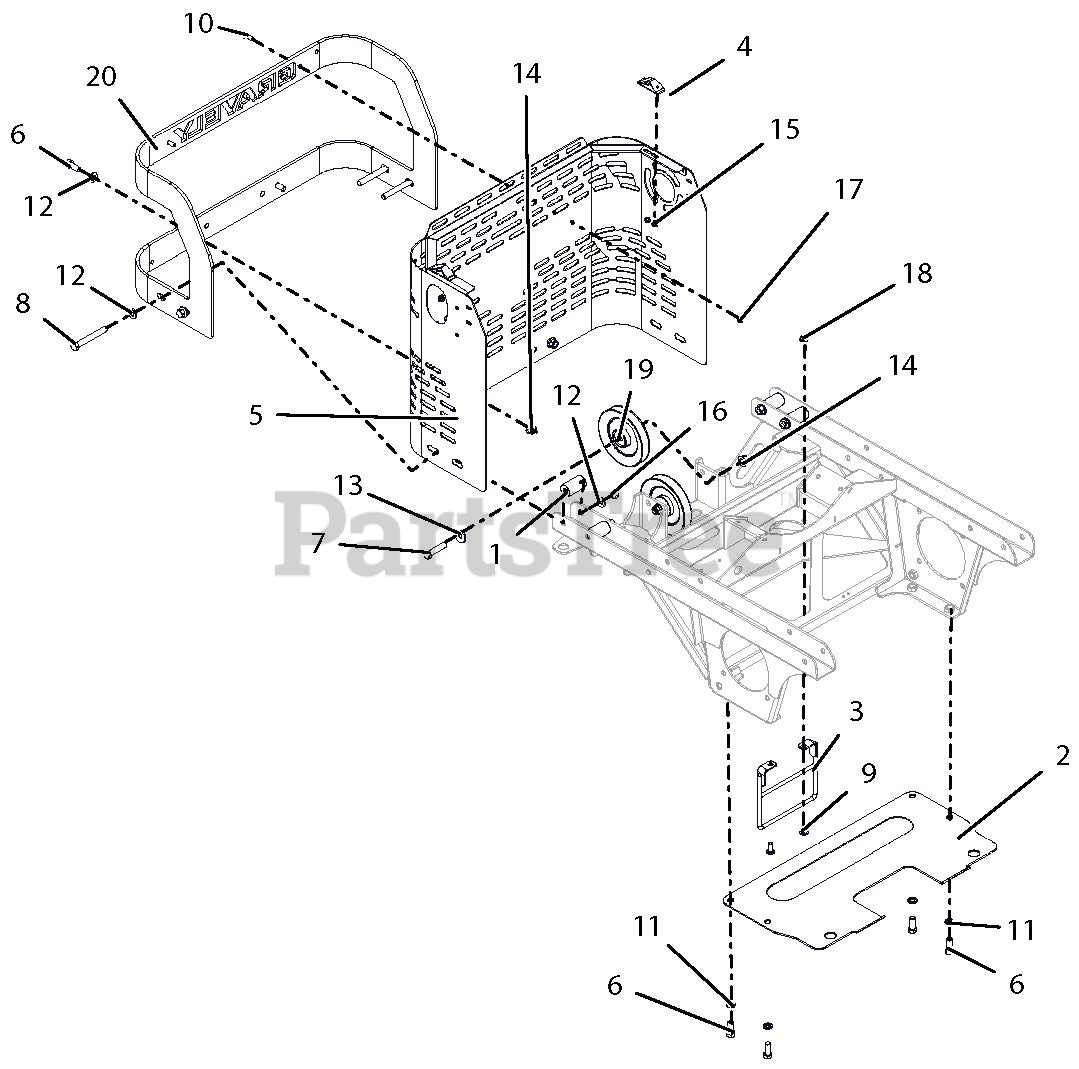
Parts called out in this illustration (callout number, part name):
1	SPCR, BUMPER MOUNT PT400 DIESE
2	PLATE-TRANSMISSION SKID
3	WDMT, DIESEL BELT FINGER-BLK
4	WDMT, HOOD MOUNT
5	WDMT, DIESEL REAR BUMPER GUARD
6	@BLT-HEX .50-13X1.25 GR5 YWZC
7	@BLT-HEX .50-13X2.25 GR5 YWZC
8	@BLT-HEX .50-13X4.00 GR5 YWZC
9	@BLT-RDHDSHSQNK.38-16X1.0 G5YZ
10	@BLT-RDHDSQNK .31-18X1.00 G5YZ
11	@WSHR-LK .50X.125 REG YWZC
12	@WSHR-FL-STL.531X1.06X.095YWZC
13	@WSHR-FL-STL.563X1.38X.109YWZC
14	@NUT-LK-NYL-FLG .50-13 YWZC
15	@NUT-SPNLK-FLG .25-20 YWZC
16	@NUT-LK-CTR .50-13 YWZC
17	@NUT-LK-NYL-FLG .31-18 YWZC
18	@NUT-LK-NYL-FLG .38-16 YWZC
19	PLY-V 6.0 X .500 ID DBL BRG.
20	REAR BUMPER W/SAFETY DECAL-DIE
